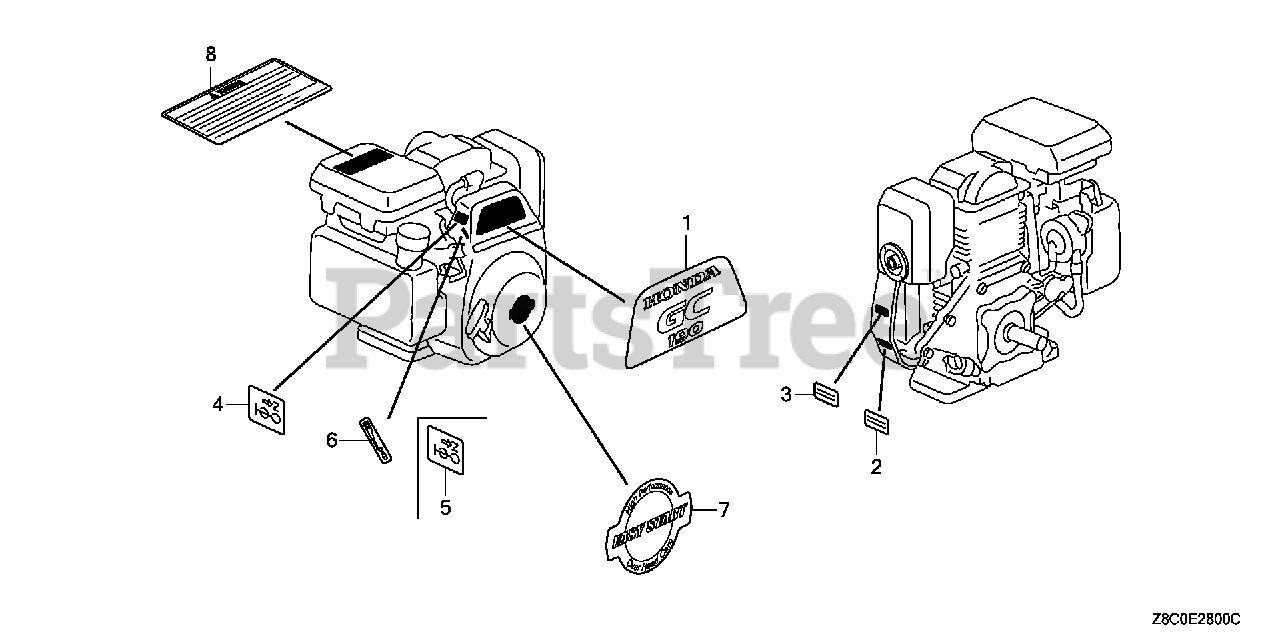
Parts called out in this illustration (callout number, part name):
1	MARK, EMBLEM (GC190)
3	LABEL, WARNING (NOT CERTIFIED FOR SALE)
5	MARK, CHOKE
7	MARK, RECOIL COVER
